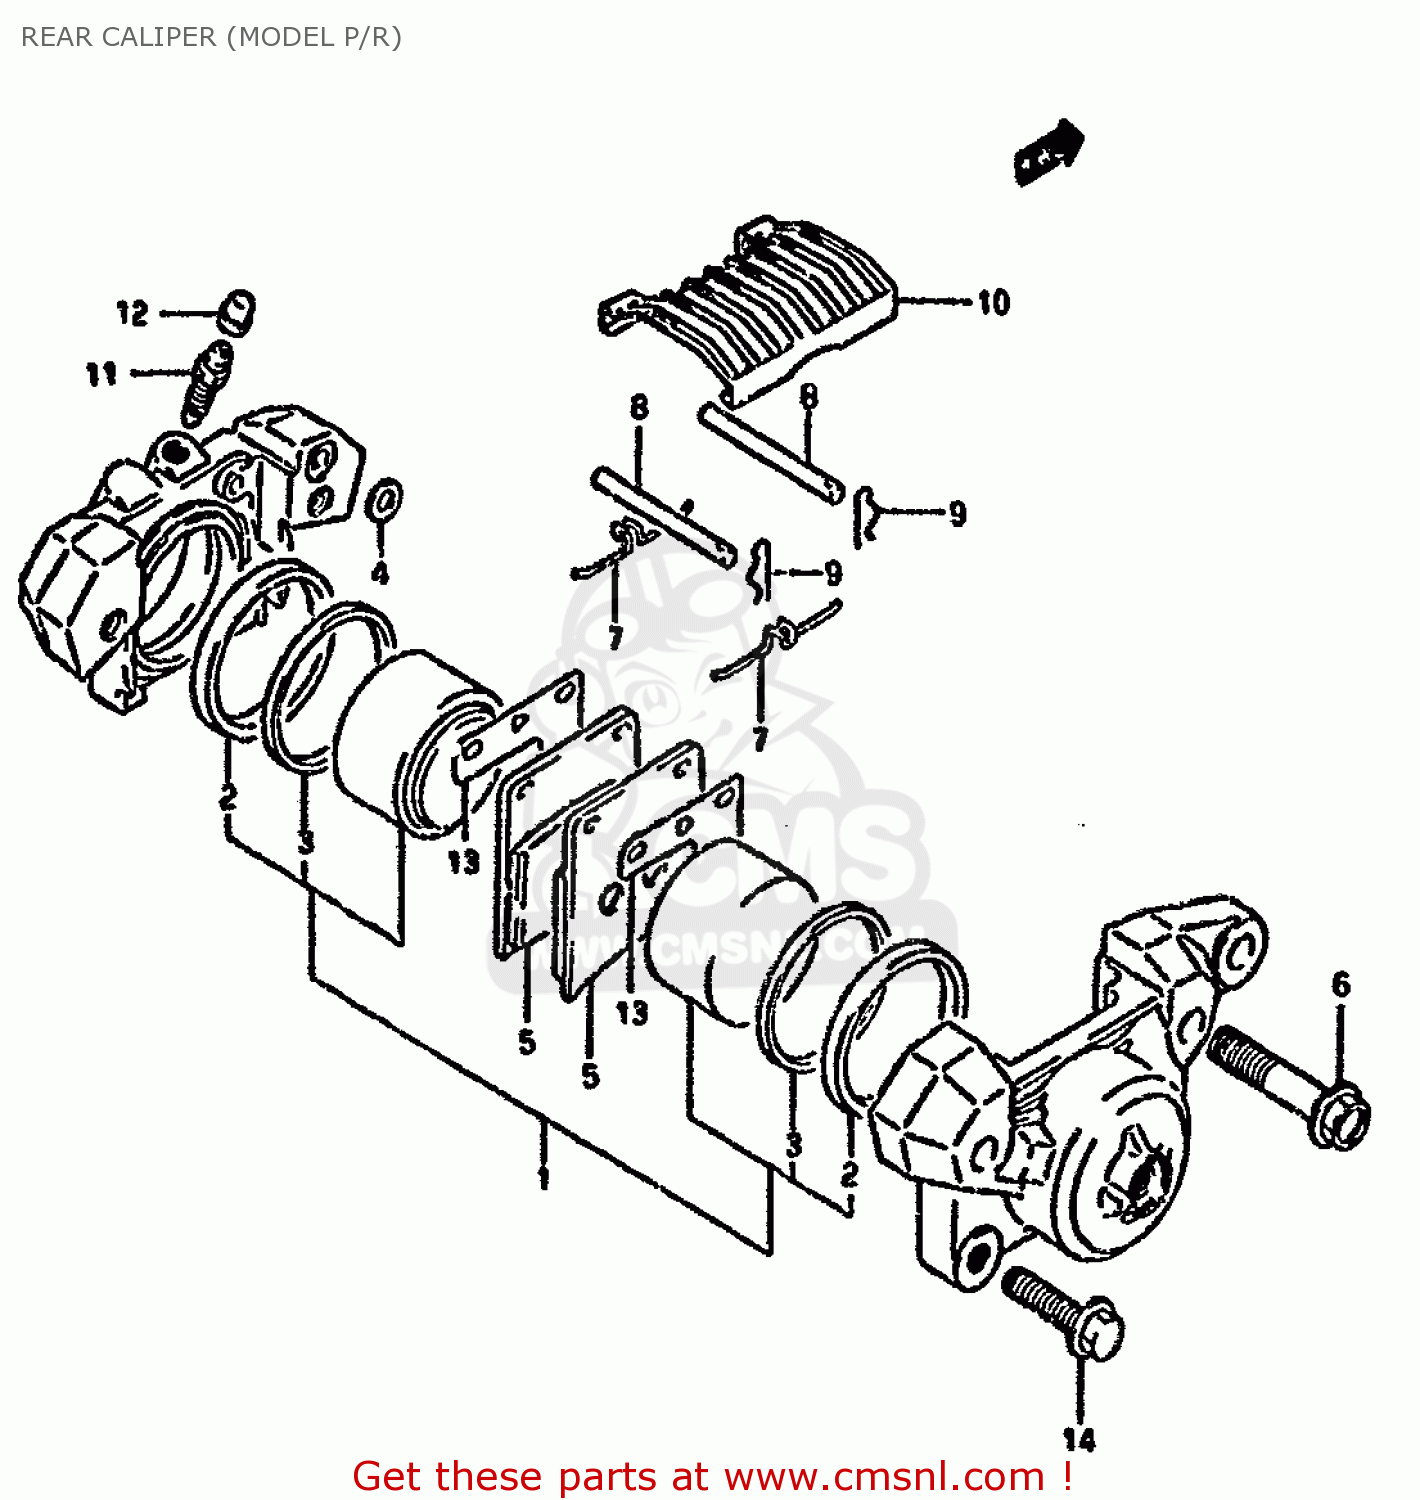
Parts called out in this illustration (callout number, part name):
1	PISTON SET
2	SEAL,FR CALIPE
3	SEAL,WIPER
4	SEAL,JOINT
5	PAD,BRAKE
6	BOLT,HOUSING
7	SPRING
8	PIN,PAD
9	CLIP,PAD PIN
10	COVER
11	BLEEDER
12	CAP,BREATHER
13	SHIM,PAD
14	BOLT
